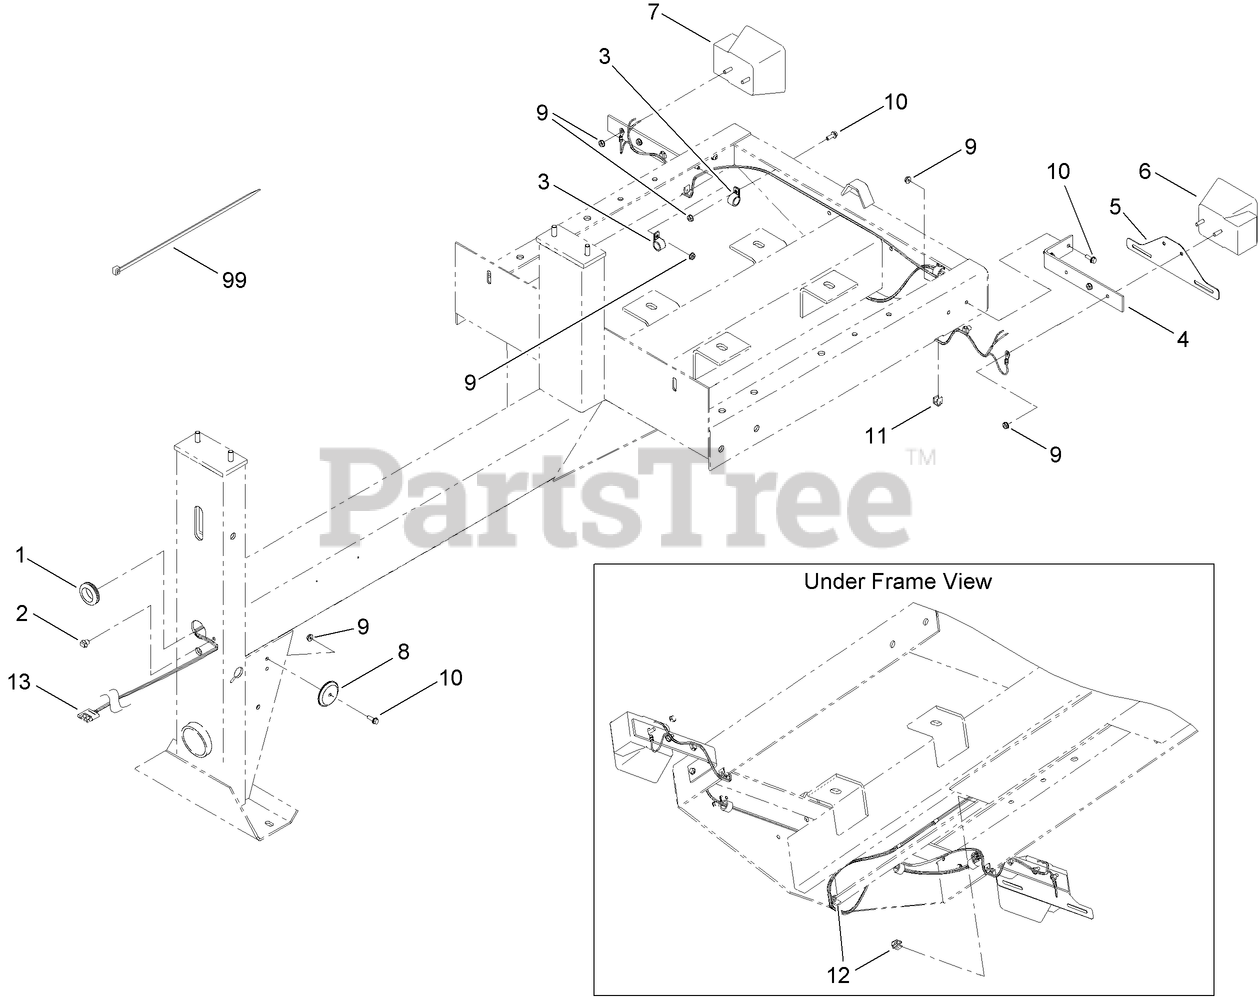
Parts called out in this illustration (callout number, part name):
1	GROMMET
2	CLIP-TIE
3	CLAMP-CABLE
4	BRACKET-UNIVERSAL
5	HOLDER-PLATE, LICENSE
6	LIGHT-TAIL, LH
7	LIGHT-TAIL, RH
8	Reflector-Amber
9	NUT-KEPS
10	SCREW-HHF
11	CLIP-EDGE
12	CLIP-EDGE W/TIE, PERPENDICULAR
13	HARNESS-WIRE, TRAILER LIGHTS
99	TIE-CABLE
